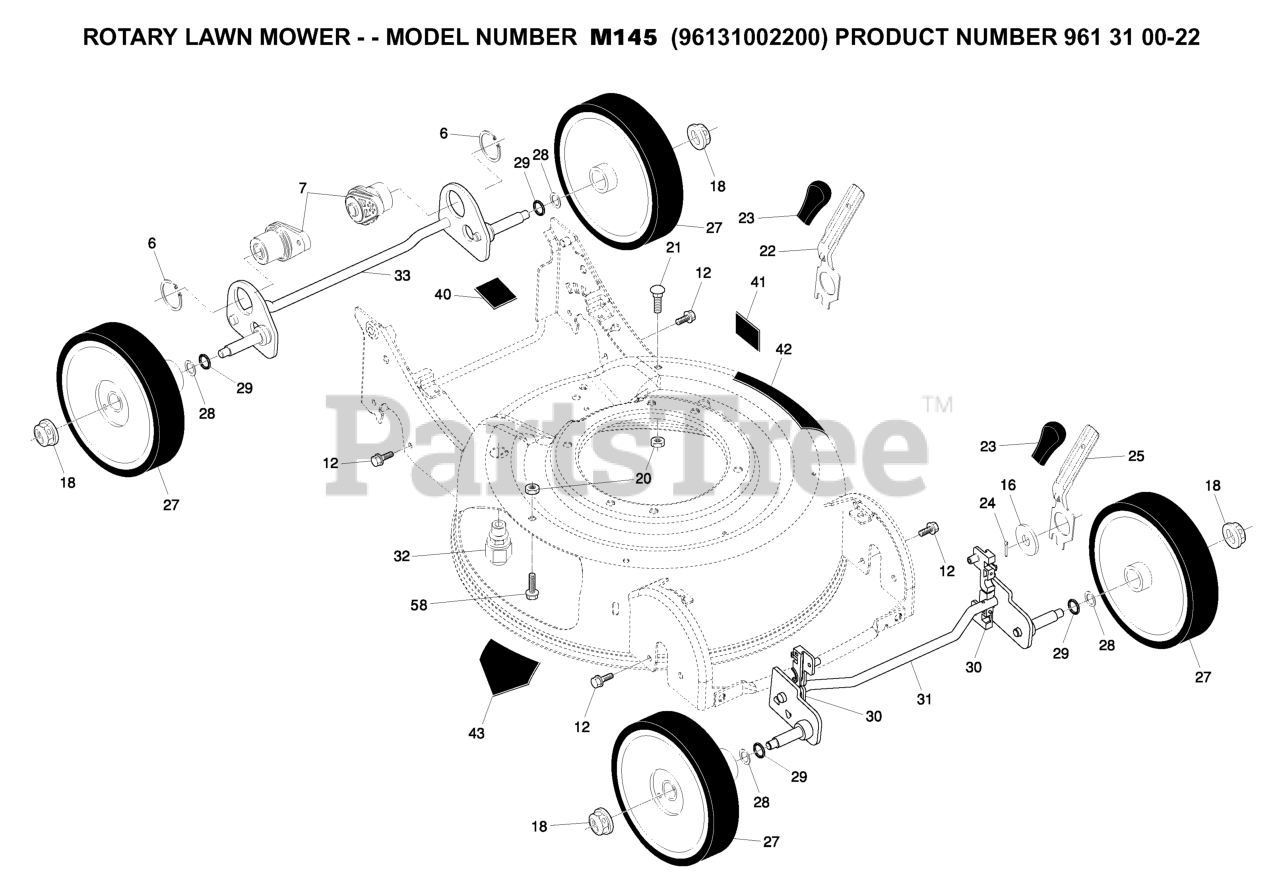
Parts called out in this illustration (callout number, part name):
6	RETAINING RING (2 2)(3 2)
18	NUT.HEX.FLANGE.3/8-16.LO(3 2)
20	NUT
21	BOLT.CARRIAGE.1/4-20 X 7/8
24	SPRING RETAINER
27	WHEEL & TIRES ASSY, FRONT
28	WASHER.FLAT.1/2
29	O-RING..070X.487.NEOPRENE
30	BUSHING.FRONT.TORQUE.S
33	AXLE.ASM.REAR.45CM.SP.BZP
43	DECAL.INTERNATIONL.CUTFINGER
